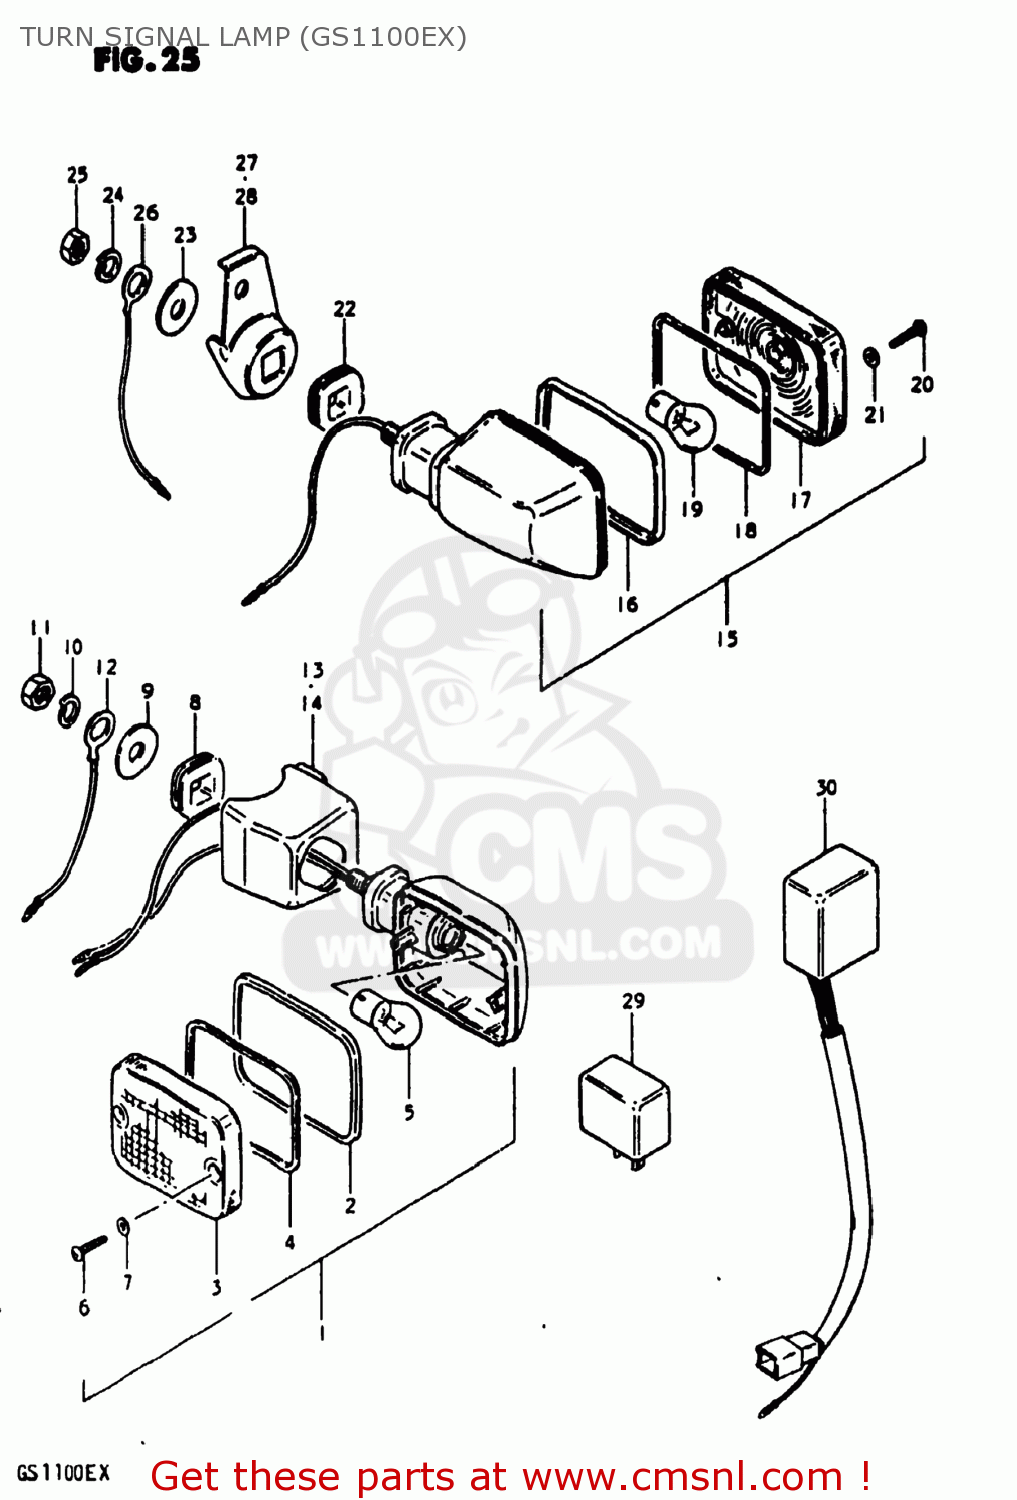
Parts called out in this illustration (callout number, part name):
1	SIGNAL LAMP
2	RIM
3	LENS
4	GASKET (NAS)
5	BULB(12V23W)
6	SCREW
7	GASKET (NAS)
8	CUSHION
9	WASHER (10.5X30X2.3)
10	LOCK WASHER
11	NUT
12	WIRE,TURN SIGNAL LEAD
13	COVER,TURN SIGNAL BRACKET
14	COVER,TURN SIGNAL BRACKET
15	LAMP ASSEMBLY,FRONT TURN SIGNAL
16	RIM
17	LENS
18	GASKET (NAS)
19	BULB(12V23W,STANLEY,A4577A)
20	SCREW
21	GASKET (NAS)
22	CUSHION
23	WASHER (10.5X30X2.3)
24	LOCK WASHER
25	NUT
26	LEAD WIRE,EARTH
27	BRACKET,REAR TURN SIGNAL
28	BRACKET,REAR TURN SIGNAL
29	RELAY ASSY,TURNSIGNAL
30	UNIT,TURN SIGNAL CONTROL
